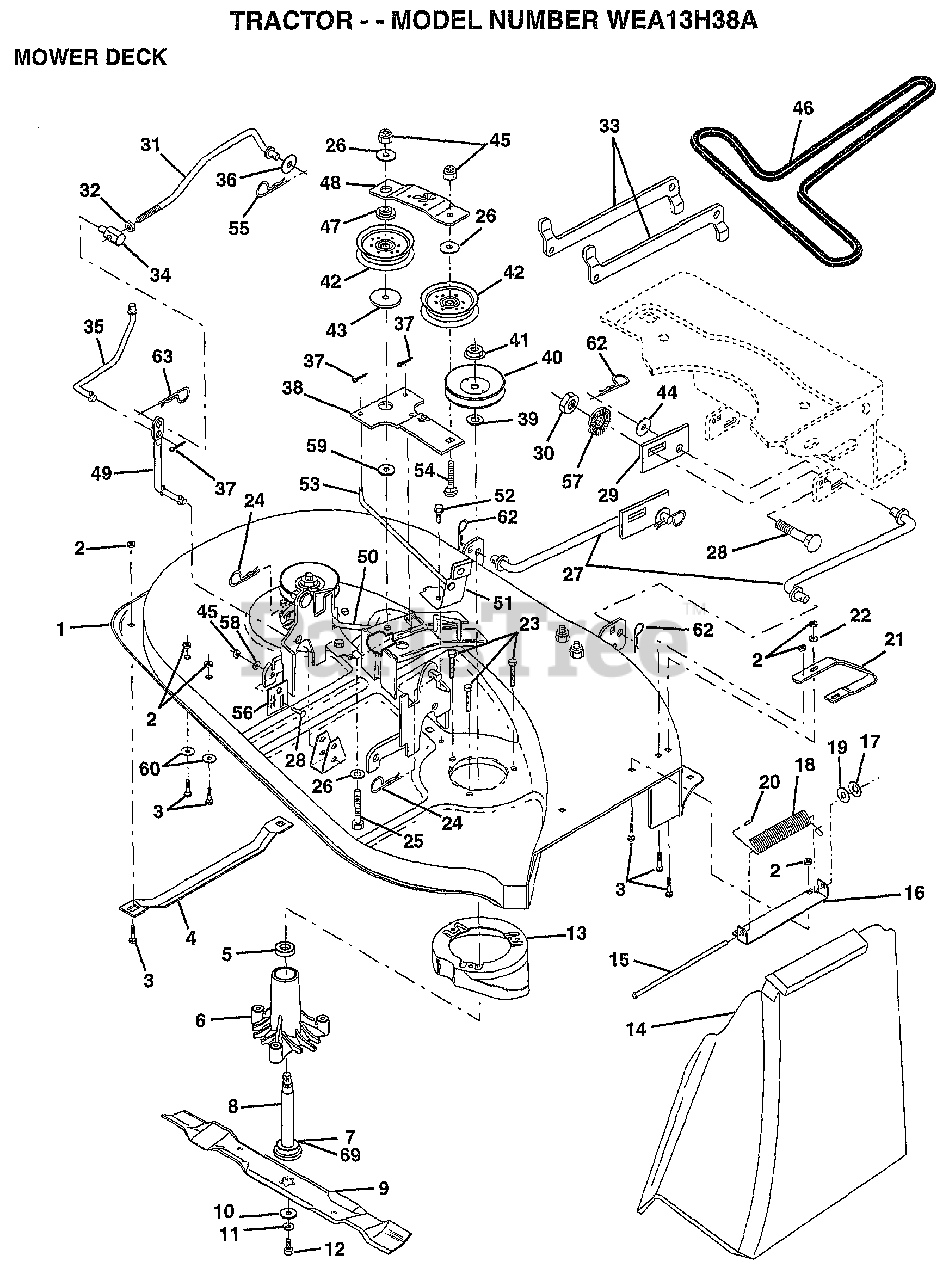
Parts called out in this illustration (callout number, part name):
1	MOWER.WELD.LR.38
3	BOLT
4	RUNNER-LH M
5	BEARING
6	HSG ASM MANDREL
7	BEARING.BALL
9	"BLADE.38"" HIPERF"
10	WASHER.HARD.BLADE
12	BLADE BOLT
13	STRIPPER RND MWR
14	DEFLECTOR-SHLD T
15	ROD-HINGE T
16	BRKT DEFLECTOR
17	NUT PUSH M
18	SPRING TORSION
19	WASHER
20	CAP-SLEEVE LT
21	RUNNER RH
22	WASHER M
23	"SCREW-THD ROLL,WA"
25	BOLT
26	WASHER GT
27	"LINK LIFT 38"""
29	PLATE SLIDE LINK
30	NUT
31	ROD.CLUTCH.PRIM
32	NUT
33	SUSP ARM REAR
34	TRUNION ADJ
35	CLUTCH ROD SEC
36	WASHER
38	IDLER ARM ASSY
39	WASHER
40	PULLEY.MANDREL.38
42	PULLEY, FLAT IDLER
43	SPACER RETAINER
44	WASHER 1/2X1 1/4
46	BELT.V.T-PATH
47	RETAINER SPACER
48	IDLER ARM STIFF
49	PIVOT ROD
50	BRAKE ROD LH
51	BRAKE ASM
52	SCREW
53	BRAKE ROD RH
54	BOLT
55	SPRING.RETAINER
56	PLATE ADJ LINK LH
57	WASHER.SERRATED.
58	WASHER T
59	HARDENED WASHER
60	WASHER.34X.68X16
62	RETAINER.SPRING
69	WASHER.FELT.
